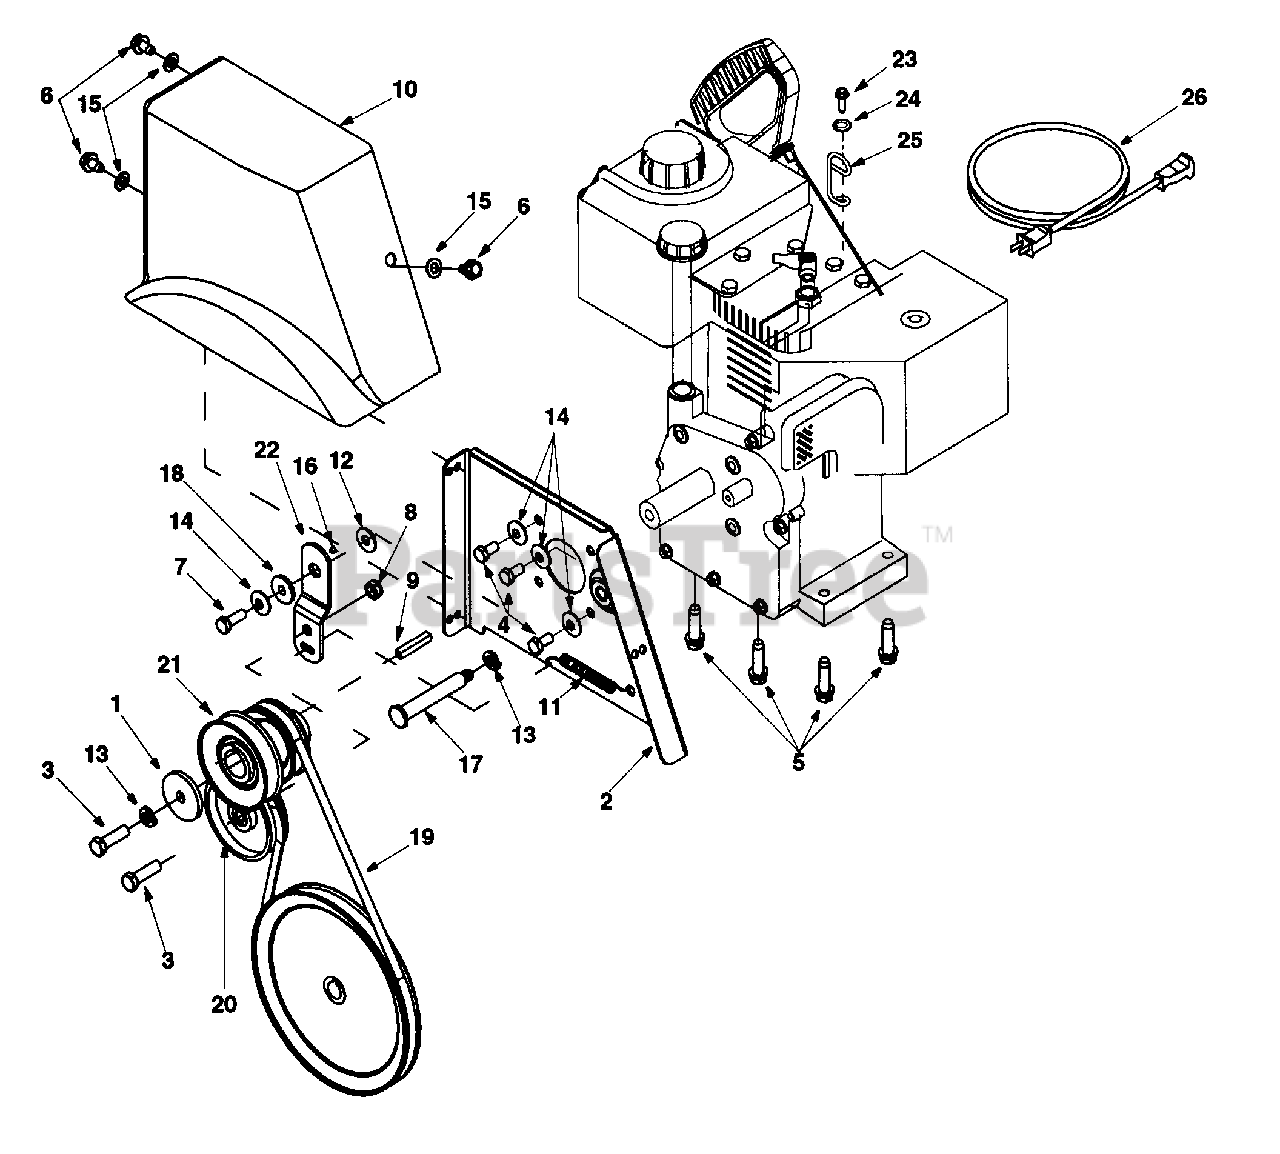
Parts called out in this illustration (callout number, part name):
4	Hex Screw 5/16-24 x .625"
5	TT Sems Screw
6	TT Screw 5/16-18 x 0.5"
7	Hex Lock Screw 5/16-24 x .875"
10	Belt Cover
11	Extension Spring
14	Beleville Washer
16	Grease
17	Shoulder Screw
18	Shoulder Spacer
19	V-Belt
21	Double Pulley
22	Idler Bracket
23	Hex Lock Nut: 1/4-20
26	Extension Cord: 110V, 3-prong
